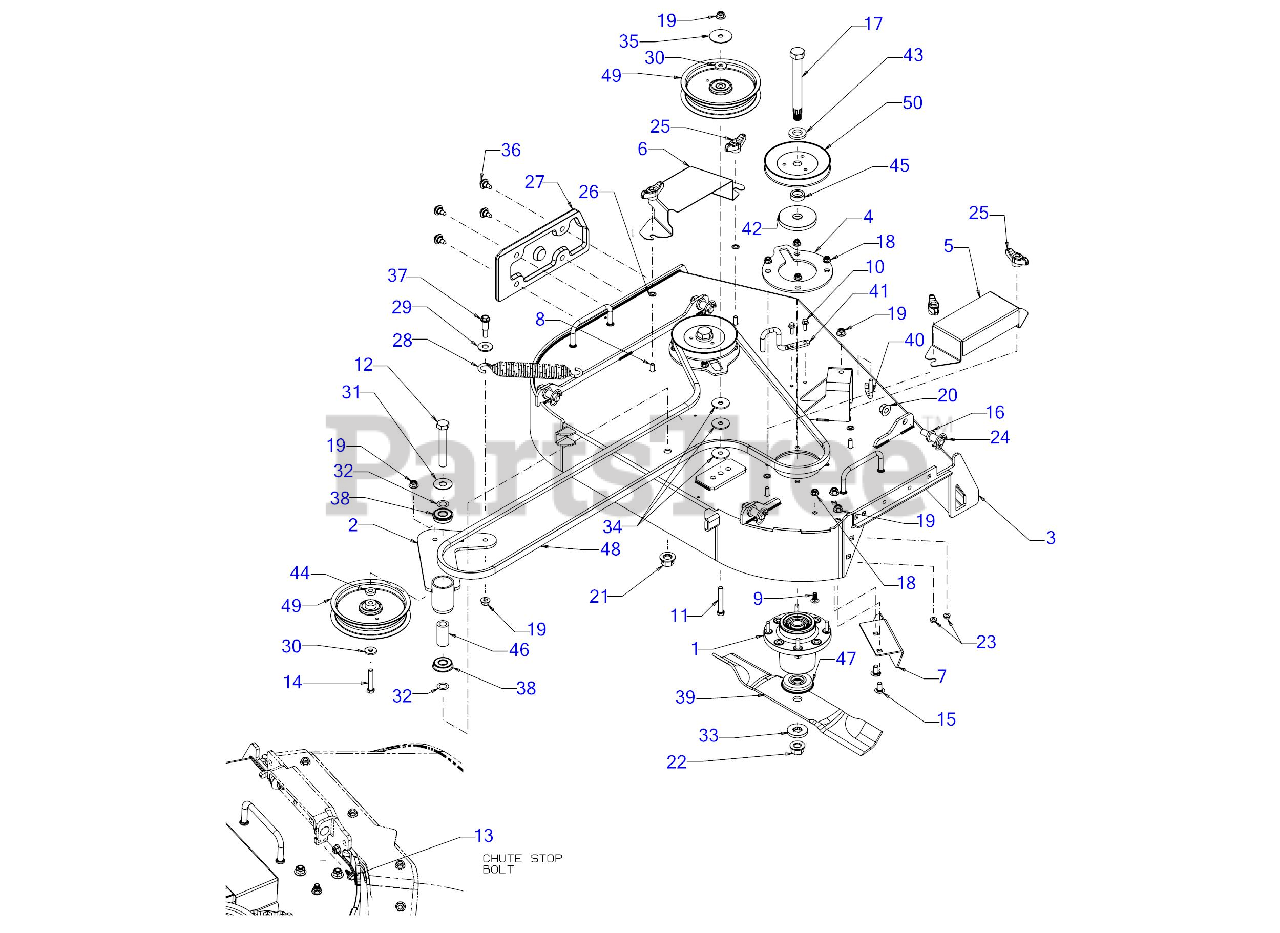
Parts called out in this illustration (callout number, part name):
1	SPINDLE ASSEMBLY
2	IDLER ARM ASSEMBLY
3	36" DECK ASSEMBLY
5	DECK BELT COVER (RH)
6	DECK BELT COVER (LH)
7	DECK CHUTE BAFFLE (LH)
8	CARRIAGE BOLT 5/16-18 x 1.00
9	CARRIAGE BOLT 5/16-18 x .75
10	SCREW 1/4-20 x .75 GR5
11	HEX SCREW-3/8-16X2.5 GR5
12	SCREW 5/8-18 x 4 GR5
13	SCREW 1/4-20X.625
14	SCREW 3/8-16 x 2.0 GR5
15	CARRIAGE BOLT 3/8-16 x .75
17	SPINDLE SHAFT
18	FLANGE LOCK NUT 5/16-18
22	FLANGE NUT - 5/8-18 GDE 8
23	LOCK NUT 1/4
25	WING KNOB 5/16-18
27	DECK SKID PLATE (LH)
28	SPRING 1.25" DIA X 8.5" LONG
29	FLAT WASHER
30	FLAT WASHER .385 x 1.00 x .135
31	FLAT WASHER-.63IDX1.595ODX.62
32	FLAT WASHER
33	FLAT WASHER - SPECIAL
34	FLAT WASHER .406X1.500X.105
35	HUB CAP WASHER .406 x 1.92 x .060
36	SHOULDER SCREW .43X.29X5/16-18 TT
37	SHOULDER SCREW .50X.925
38	BALL BEARING
39	18.50" BLADE (HI LIFT)
40	ROD SPRING HOOK
41	BELT KEEPER ROD
42	DECK SPINDLE SPACER
43	SPACER .812 ID x .218 LG
45	SPACER (.792 X 1.20 X .380)
46	SPACER 0.63 X 1.00 X 2.01
47	SPACER 0.790 X 2.75 X 0.486
48	V-BELT B-SEC x 108.25"
49	IDLER PULLEY (6.00" DIA)
50	SPINDLE PULLEY (5.625")
